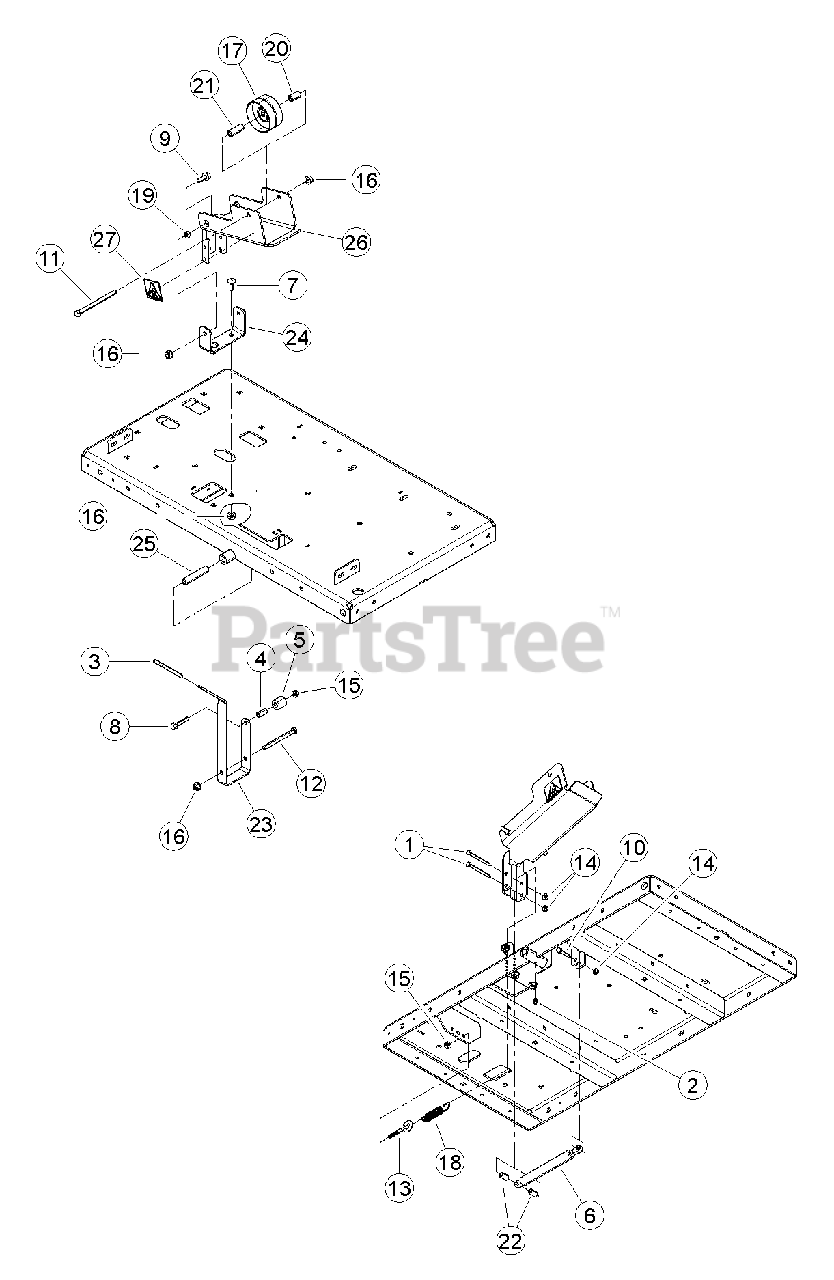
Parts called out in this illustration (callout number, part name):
1	BOLT, 1/4 X 2-3/4 HEX GR 5 ZP
2	FITTING, 1/4 SELF-TAP GREASE
3	GRIP, CLUTCH HANDLE
4	SPACER, 0.5 X 1.00
5	ROLLER, 0.5 X 1.00 X 1.00 NYLON
6	DAMPER, IDLER
7	BOLT, 3/8 X 1 CRG GR5 NC ZP
8	BOLT, 5/16 X 1-3/4 FLANGE NC
9	BOLT, 3/8 X 1 FLANGE NC
10	BOLT, 1/4 X 1-1/4 FLANGE NC
11	BOLT, 3/8 X 5 HEX GR5 ZP
12	BOLT, 3/8 X 4 HEX GR5 NC ZP
13	I-BOLT, 5/16-18 X 2 ZP
14	NUT, 1/4-20 NYLOCK-FLANGE
15	NUT, 5/16-18 NYLOCK-FLANGE
16	NUT, 3/8-16 NYLOCK FLANGE
17	PULLEY, 3-1/4 FLAT IDLER
18	SPRING, 3/4"OD EXTENSION
19	SPACER IDLER PIVOT
20	IDLER SPACER
21	SPACER .63 X 1.63
22	SPACER, .50 X .775
23	LEVER, CHIPPER ENGAGEMENT
24	ANCHOR, IDLER
25	SPACER, .63 X 3.060
26	BRACKET, IDLER SERVICE PART
27	DECAL, SHIELD DANGER ISO
